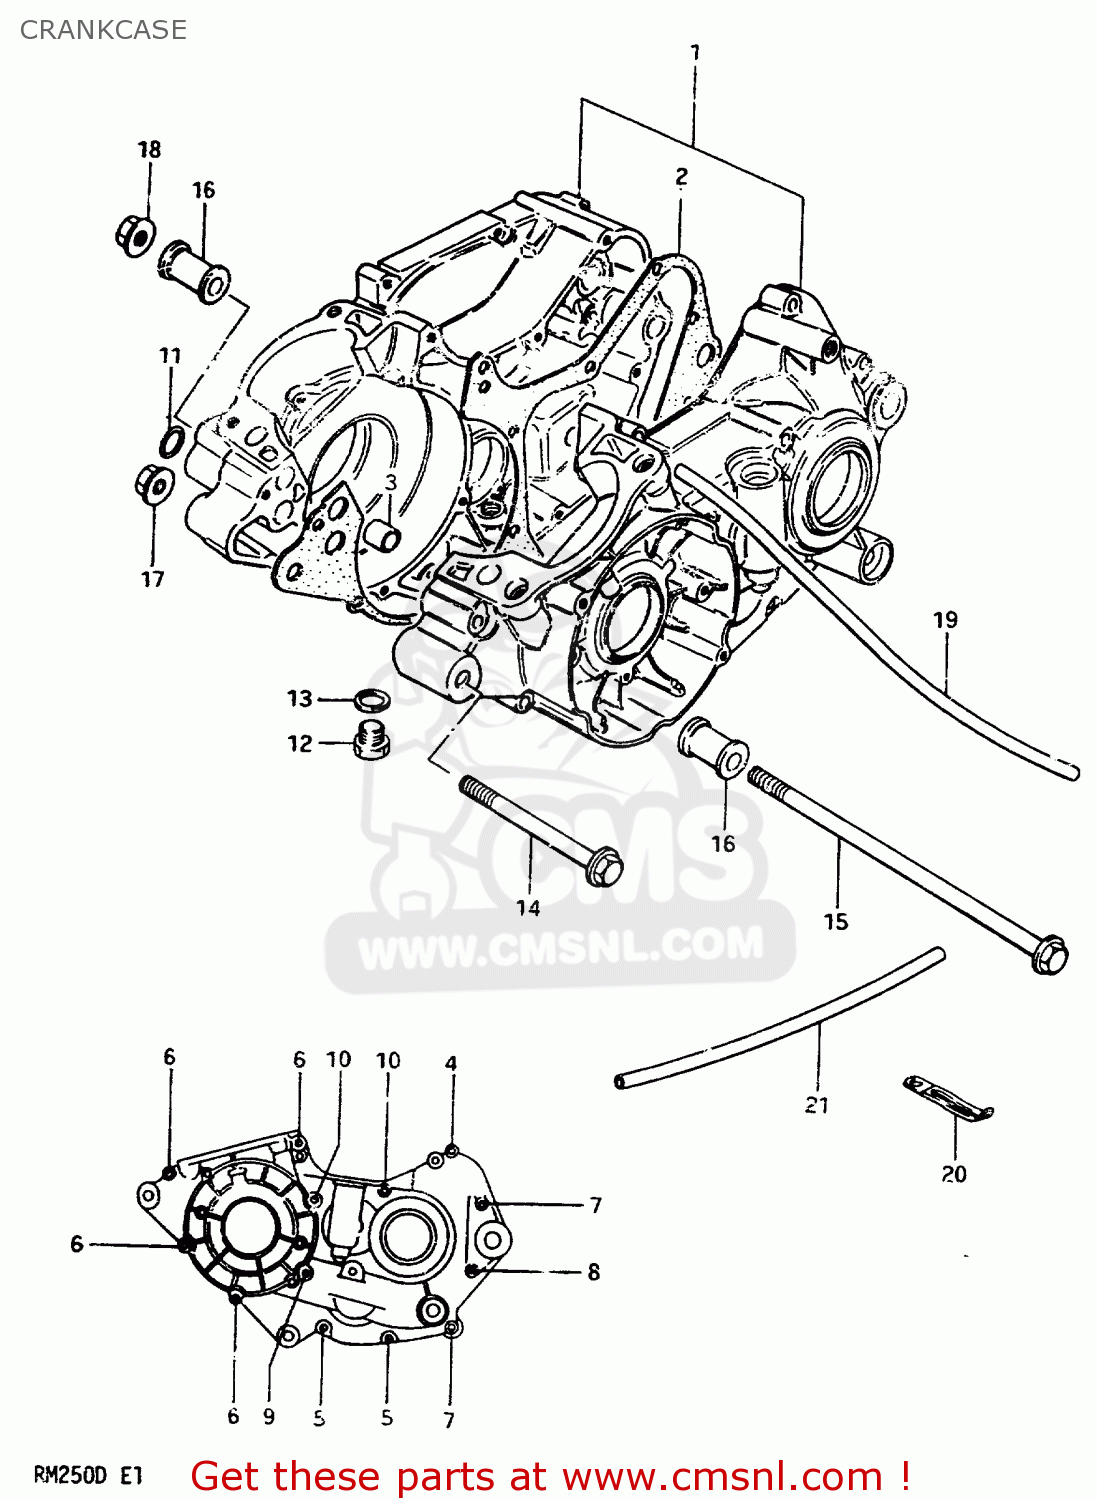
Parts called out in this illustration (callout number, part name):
1	CRANKCASE SET
2	GASKET,CRANKCASE (NAS)
3	PIN
4	SCREW 6X30
5	SCREW
6	SCREW
7	SCREW
8	SCREW
9	SCREW 6X60
10	SCREW 6X70
11	O RING(D:1.9,ID:13.8)
12	PLUG
13	GASKET(14X19.2X2) (NAS)
14	BOLT(8X100)
15	BOLT 8X220
16	SPACER,ENGINE MOUNT
17	NUT
18	NUT
19	HOSE(4X7X600)
20	CLAMP
21	HOSE(4X7X600)
